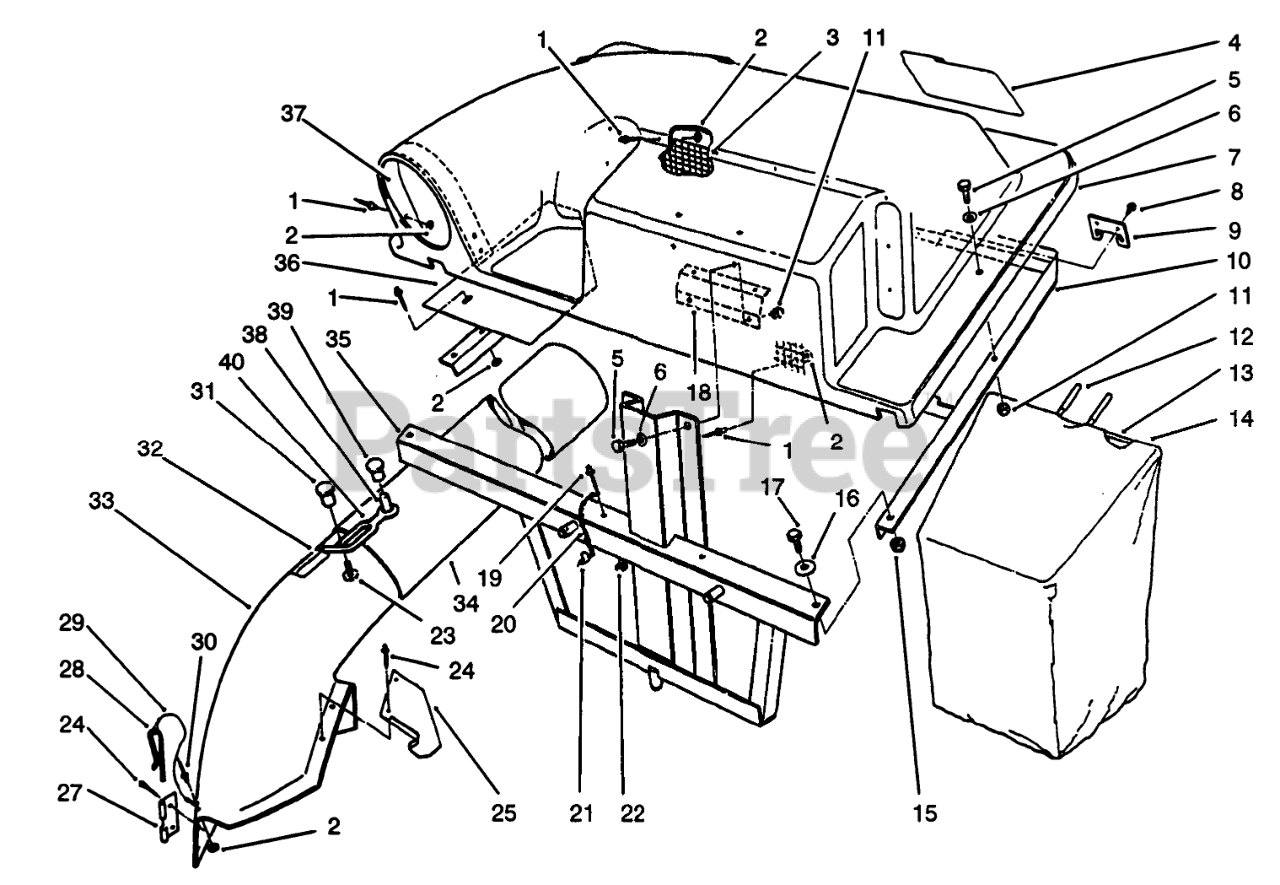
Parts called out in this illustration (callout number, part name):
1	RIVET-POP
2	WASHER-PLAIN
3	SCREEN
4	DECAL-BAGGER, TWIN
5	SCREW-HH
6	WASHER-PLAIN
7	COVER-BAGGER, TWIN
8	SCREW-HWH
9	BRACKET-FRAME, BAG
10	Cover-Frame
11	NUT-LOCK, NI
12	GRIP-HANDLE, BAG
13	Frame-Bag
15	NUT-LOCK, NI
16	WASHER-FLAT
17	SCREW-HH
18	Plate-Backup
20	10 LINK CHAIN W/O HOOK
21	PIN-HAIR
22	WASHER-BACK
23	Screw
24	RIVET-BLIND
25	CHUTE SUPT BRKT
27	BRACKET-MOUNTING, CHUTE
28	PIN-LOCKING, CHUTE
29	LANYARD
30	RIVET-BLIND
32	DECAL-DANGER
33	Assembly-Chute (Incl. Ref. #2. 23-32)
34	TUBE(ROUND&LONG)
35	Frame-Mounting
36	Baffle
37	Support Inlet
38	SPACER-INTERLOCK
39	FASTENER-PANEL
40	RETAINER-DUCT
